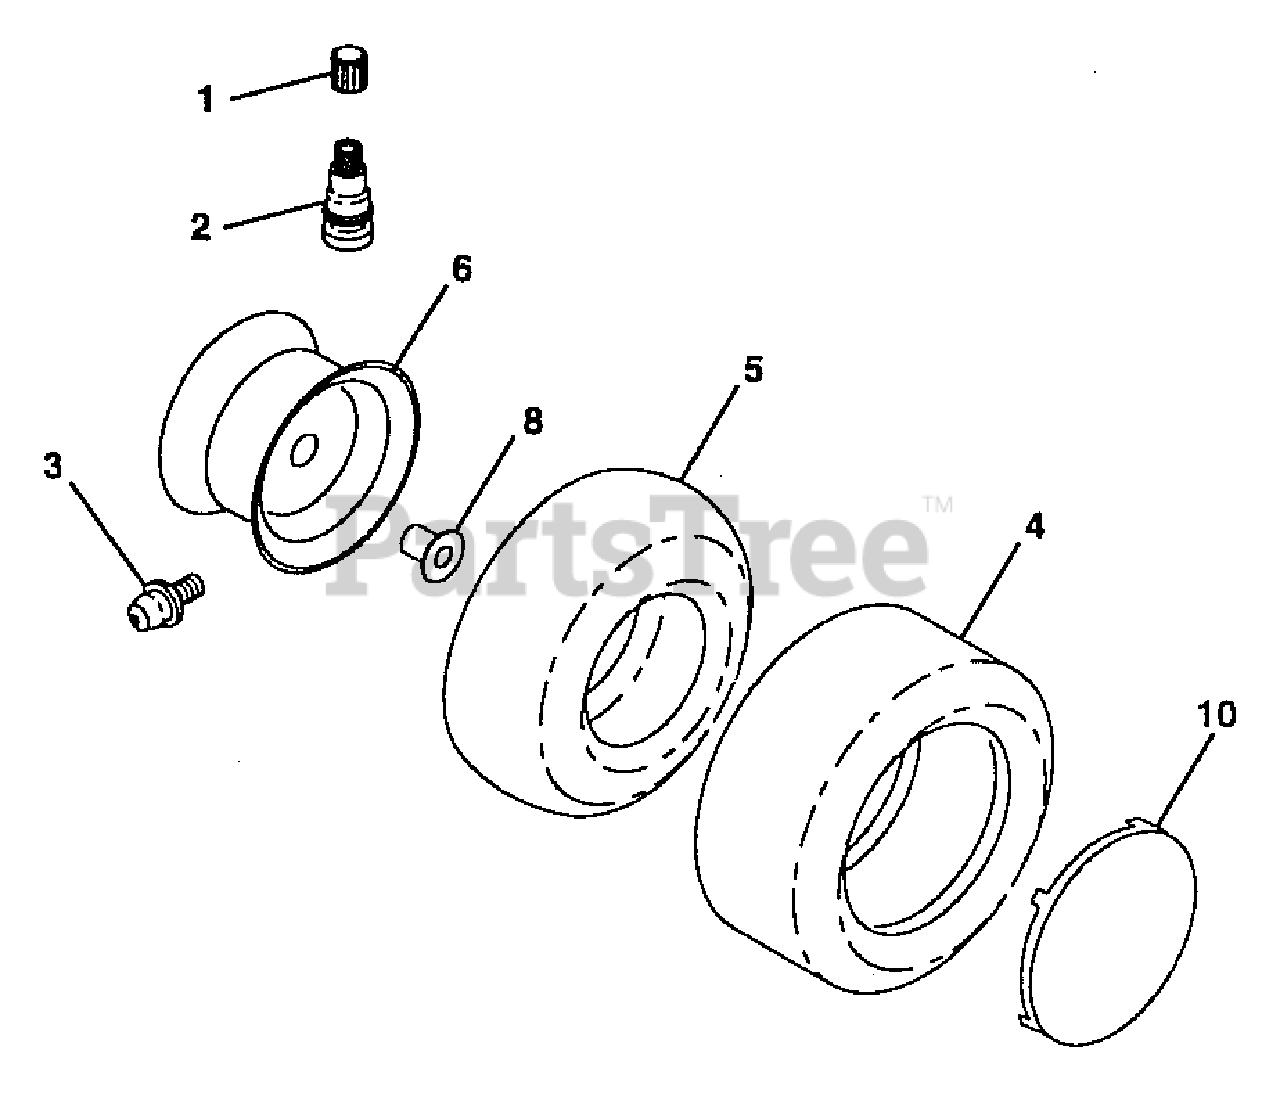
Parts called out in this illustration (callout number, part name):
1	Cap Valve Tire
2	Stem Valve
3	Fitting Grease
4	Tire F Ts 15 X 60- 6 Service
4	Tire R Ts 20 X 10 - 8 Service
5	Tube Front
5	Tube Rear
6	Rim Asm 8" rear White Service
6	Rim Asm 6" front White Service
8	Bearing Flange
10	Cover Wheel 6" white
10	Cover Wheel 8" white
